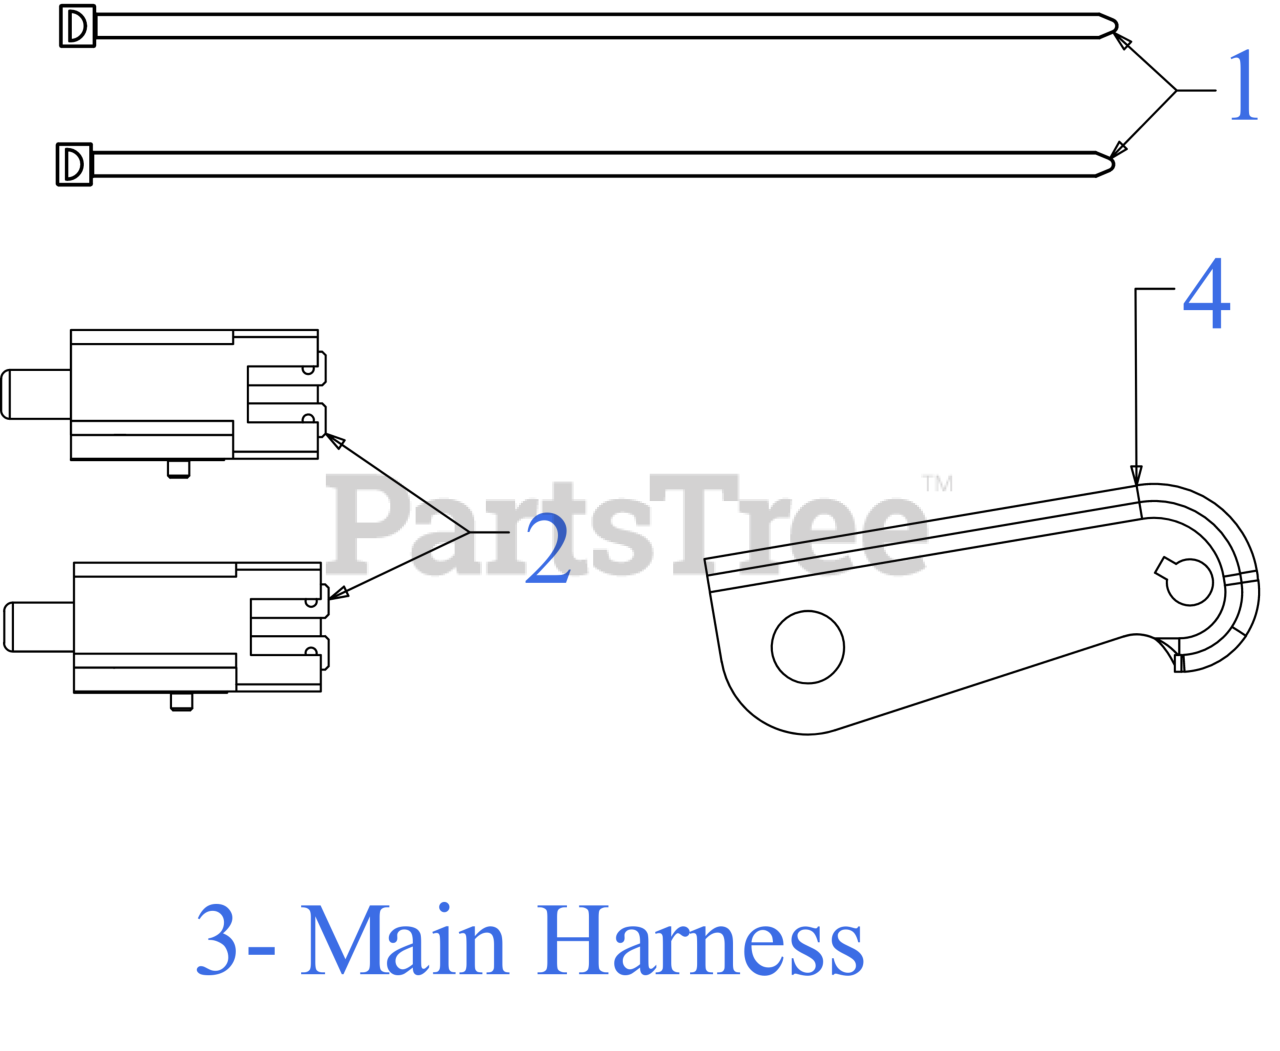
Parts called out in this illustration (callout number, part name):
1	7" CABLE TIE
2	INTERLOCK SWITCH (NO/NC)
3	MAIN HARNESS (RMC/AM/ACDC/BULB AGM)
3	12V SOLENOID
4	LATCH SPEED BRACKET
